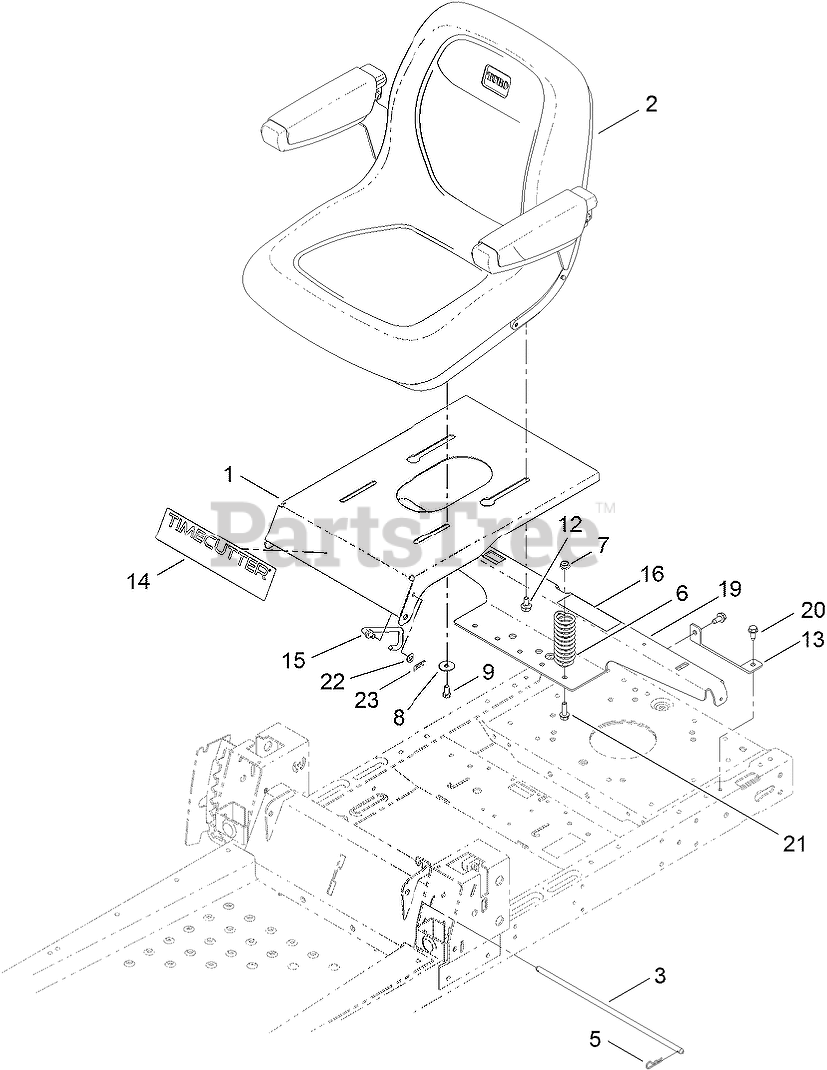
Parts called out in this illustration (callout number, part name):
1	PAN-SEAT
2	SEAT-18 Inch
3	ROD-PIVOT, NARROW
5	PIN-COTTER
6	SPRING-COMPRESSION
7	NUT-HF, NI
8	WASHER-PIVOT
9	SCREW-HH
12	BOLT-SHOULDER
13	SUPPORT-TANK, REAR
14	DECAL-TIMECUTTER
15	STOP-SEAT
16	DECAL-SERVICE, CE
19	SUPPORT-POD
20	SCREW-HWHTF
21	SCREW-HHF
22	WASHER-PLAIN
23	PIN-COTTER
